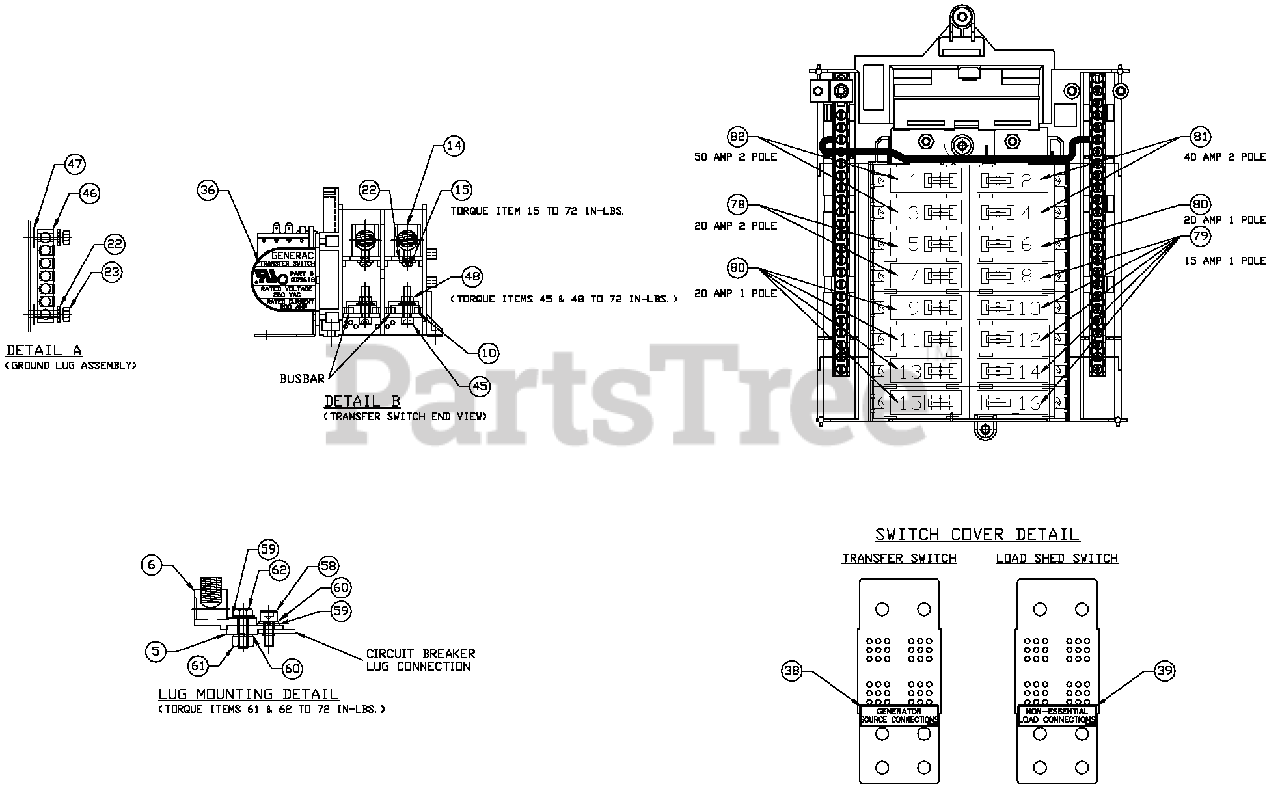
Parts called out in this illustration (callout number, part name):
5	BUSBAR, 200A LUG ADAPTER
6	LUG 300 MCM-6STR
10	BUSBAR, 200A TRANSFER SW T2
14	LUG SOLDERLESS 250-#6 AL/C U
15	SCREW BHSC 1/4-20X3/8
22	WASHER LOCK M6-1/4
23	NUT HEX 1/4-20 SS
36	DECAL, TRANSFER SWITCH INFO
38	DECAL, GENERATOR SO URCE CONNECTION
39	DECAL, NON-ESSENTIAL LOAD CONN
45	SCREW BHSC 1/4-20X3/4
46	GROUND BAR (5) 2-14 AWG CONN
47	WASHER SHAKEPROOF EXT 1/4 STL
48	NUT HEX FL WHIZ 1/4-20
58	SCREW SHCM8-1.25X 20 G8
59	WASHER FLAT 5/16-M8 ZINC
60	WASHER LOCK M8-5/16
61	NUT HEX M8-1.25 G8 CLEAR ZINC
62	SCREW HHCM8-1.25X 25 C8.8
78	CB0 020A 2P PLUGIN
79	CB0 015A 1P PLUGIN
80	CB0 020A 1P PLUGIN
81	CB0 040A 2P PLUGIN
82	CB0 050A 2P PLUGIN
